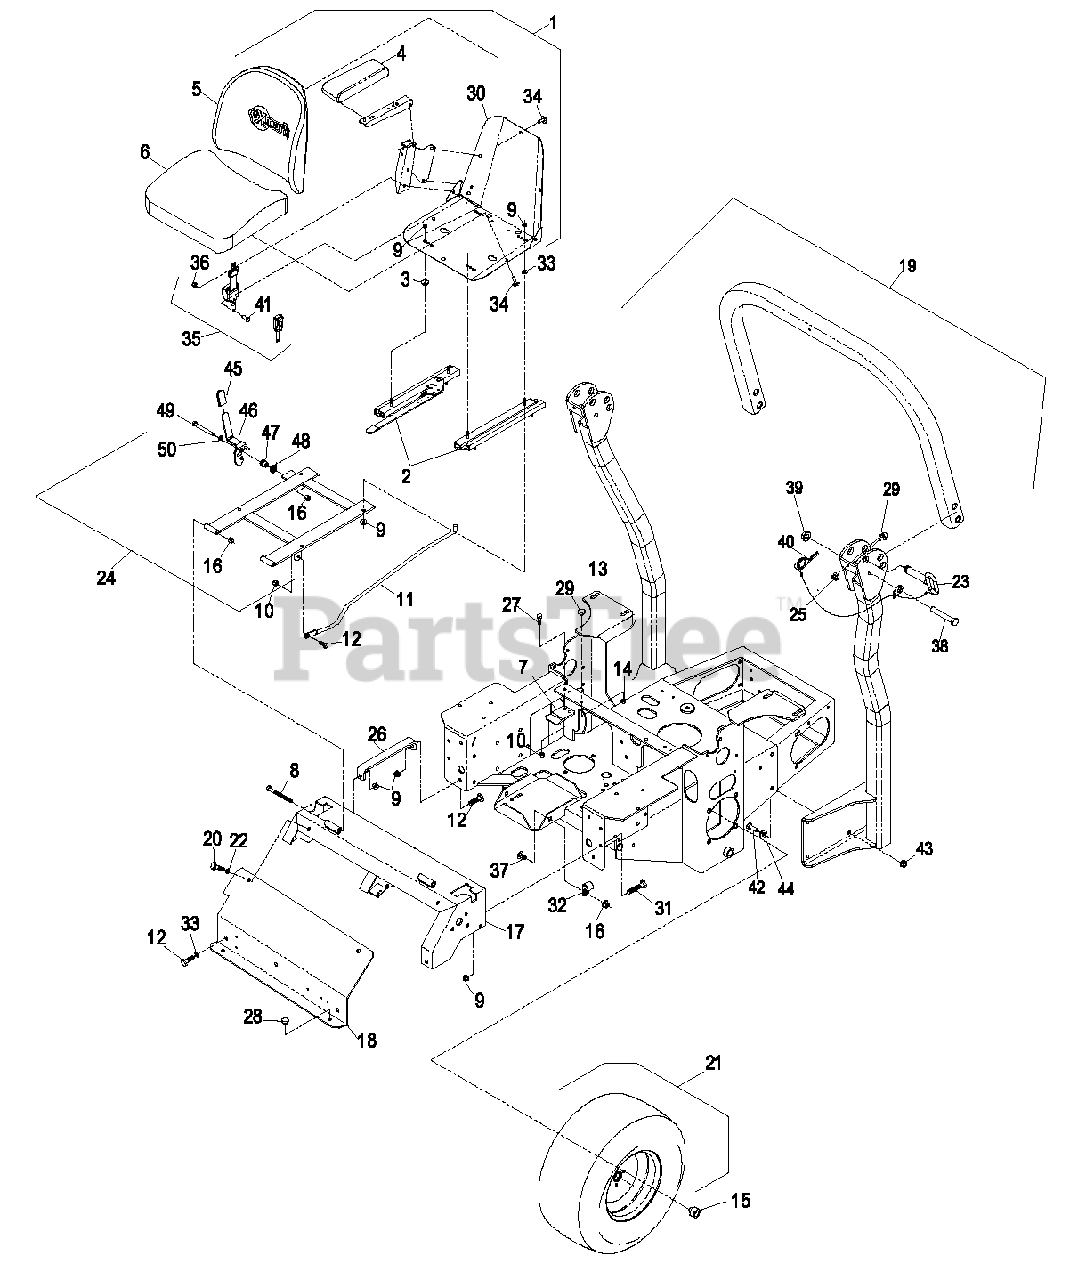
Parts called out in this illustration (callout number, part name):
1	KIT,SEAT W/ARMREST ADJ.
2	TRACK-SEAT
3	SPACER-TRACK
4	CUSHION,ARMREST RH
5	CUSHION,SEAT BACK
6	CUSHION,SEAT BOTTOM
7	CATCH-LATCH, SEAT
8	SCREW-HH
10	NUT-LOCK, NI
11	ROD-RETAINER, SEAT
12	SCREW-HH
13	ASM,MAINFRAME W/DECALS
15	NUT-LUG
16	NUT-LOCK, NI
17	ASM, CONSOLE W/DECALS
19	KIT, LAZER HP / CT 2 POST
20	SCREW-HH
21	ASM,WHEEL AND TIRE
21	WHEEL AND TIRE ASM
21	TIRE
22	WASHER-PLAIN
23	PIN-FOLD, ROPS
24	ASM,SEAT FRAME
25	NUT-LOCK, NI
26	BRACKET-PANEL, INSTRUMENT
27	SCREW-HH
29	BUMPER-RUBBER
30	FRAME-SEAT
31	SCREW-HH
32	CLIP-LOOM
33	WASHER-FLAT
34	BOLT-SEAT
35	RETRACTABLE SEATBELT KIT
36	NUT-LOCK
37	SCREW-CARR
38	SCREW-HH
40	HAIRPIN
41	SCREW-HH
42	SCREW-HH
43	NUT-HHF, WHIZ
44	WASHER-BELLEVILLE
45	GRIP-LEVER
46	LATCH ASM
47	BUSHING-LATCH, SEAT
48	SPRING-TORSION
49	SCREW-HH
50	WASHER-FLAT
